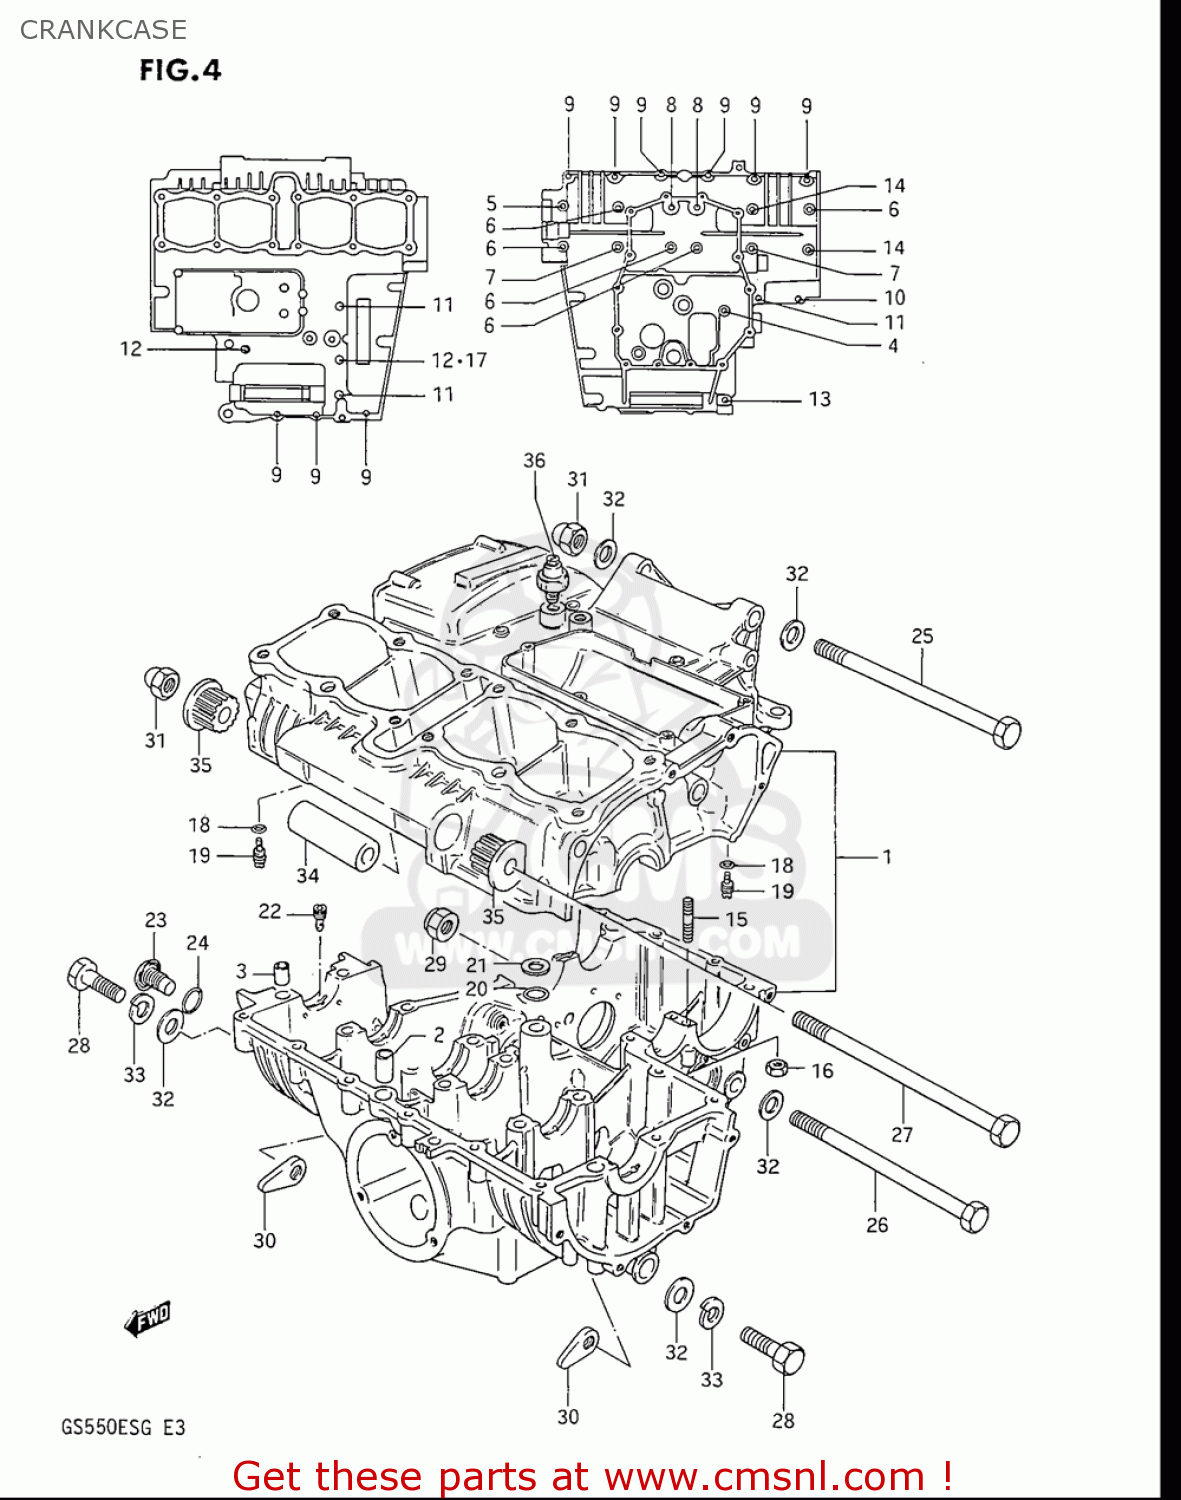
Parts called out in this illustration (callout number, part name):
2	PIN(10.4X13X22)
3	PIN(8.4X11X20)
4	BOLT(6X100)
5	BOLT(8X100)
6	BOLT(8X110)
7	BOLT(8X120)
8	BOLT
9	BOLT
10	BOLT, HYDRAULIC UNIT NO.2
11	BOLT
13	BOLT
14	BOLT
15	BOLT,STUD
16	NUT
17	GASKET(6.2X13X1.2) (NAS)
18	O RING(D:1.2,ID:4)
19	JET,OIL GALLERY
20	O RING(D:3.2,ID:12.9)
21	SHIM(10X20X1)
23	PLUG
24	O RING(D:2.4,ID:16.8)
25	BOLT
26	BOLT(10X165)
27	BOLT(10X195)
28	BOLT
29	NUT
30	NUT
31	NUT
32	WASHER
33	WASHER,LOCK
35	BUSH
36	SWITCH ASSY,OIL PRESSURE
